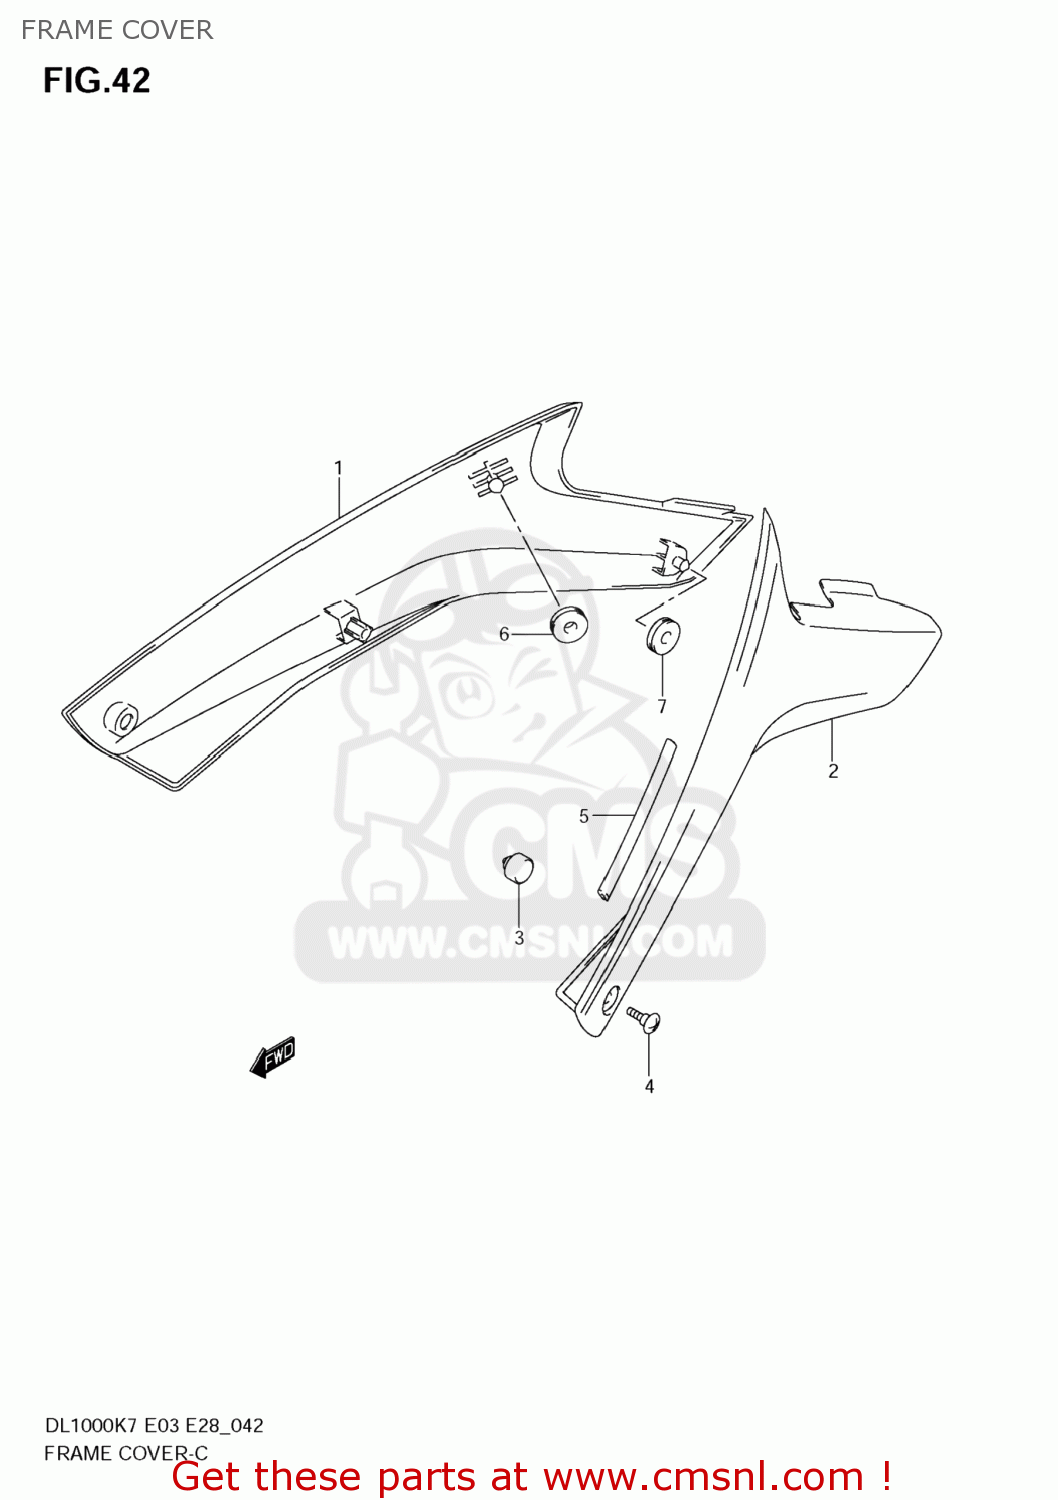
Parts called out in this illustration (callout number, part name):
1	COVER,FRAME,R(BLACK)
2	COVER,FRAME,L(BLACK)
3	CUSHION(11.5X22X20)
4	SCREW(6X16)
5	MOLDING
6	CUSHION
7	CUSHION
